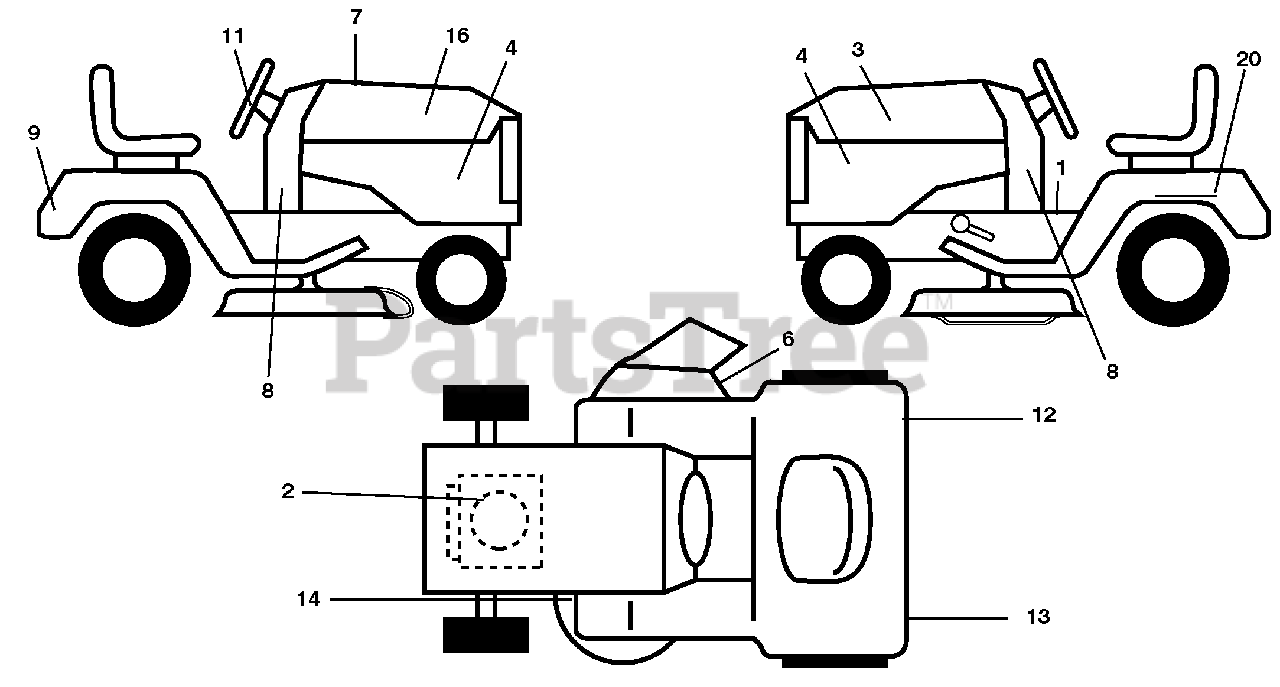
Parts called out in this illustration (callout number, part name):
1	Decal Fender Warning
2	Decal Engine H.P.
3	Decal Hood LH
4	Decal Side Panel
6	Decal Warning, Keep Hand Away
7	Decal Replacement Parts
8	Decal LWRDASH
9	Decal Fender Logo
11	Decal Ins Strg Whl
12	Decal Fender SD RH
13	Decal Fender SD
14	Decal V-Belt Schematic
16	Decal Hood RH
20	Decal Bat Dan/Psn
20	Pad Footrest LH
20	Pad Footrest RH
20	Decal Bypass
20	Manual Operator's E&F
20	Manual Parts
